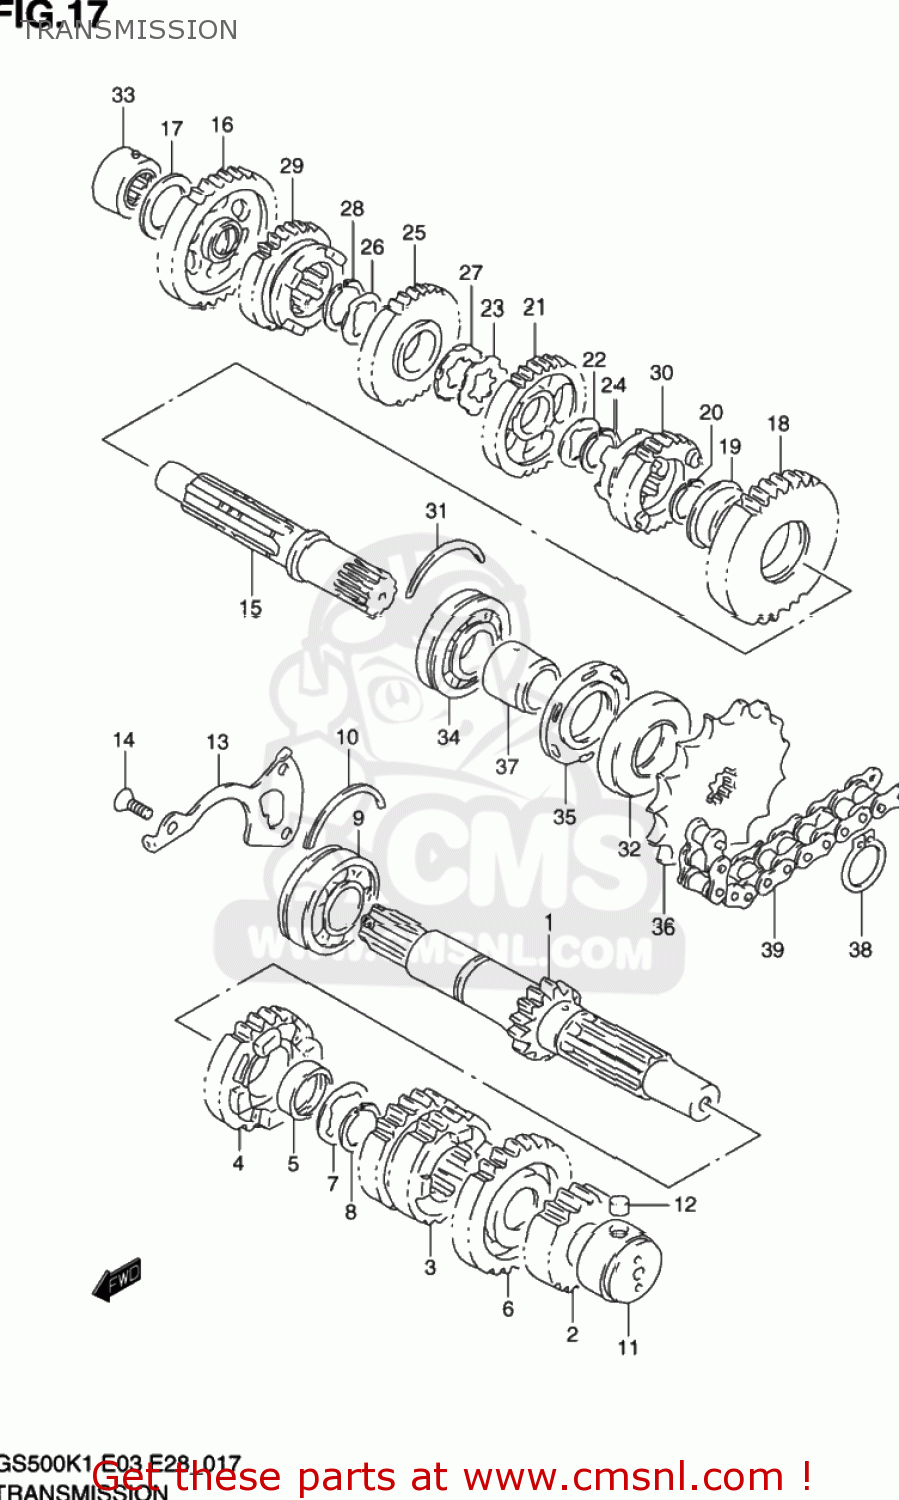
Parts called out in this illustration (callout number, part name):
1	SHAFT,COUNTER
2	GEAR,2ND DRIVE(NT:18)
3	GEAR,THIRD/FOURTH DRIVE (NT:
4	GEAR,FIFTH DRIVE (NT:26)
5	BUSH
6	GEAR,6TH DRIVE
7	SHIM(25X34X1)
8	CIRCLIP
9	BEARING(25X62X17)
10	C RING
11	BEARING(20X34X20)
12	PIN
13	PLATE,COUNTERSHAFT BEARING
14	SCREW(6X16)
15	SHAFT,DRIVE
16	GEAR,1ST DRIVEN
17	SHIM(20X34X1)
18	GEAR,SECOND DRIVEN (NT:32)
19	BUSHING
20	CIRCLIP
21	GEAR,3RD DRIVEN
22	WASHER,LOCK
23	WASHER,LOCK
24	CIRCLIP
25	GEAR,4TH DRIVEN
26	WASHER,LOCK
27	WASHER
28	CIRCLIP
29	GEAR,5TH DRIVEN(NT:25)
30	GEAR,6TH DRIVEN(NT:23)
31	C RING
32	SEAL,OIL(32X62X7)
33	BEARING(20X34X17)
34	BEARING(25X62X17)
35	SEAL,OIL(32X62X5.5)
36	SPROCKET,ENGINE(16T)
37	SPACER,ENGINE SPROCKET
38	CIRCLIP
39	CHAIN(DID520VM,110L)
